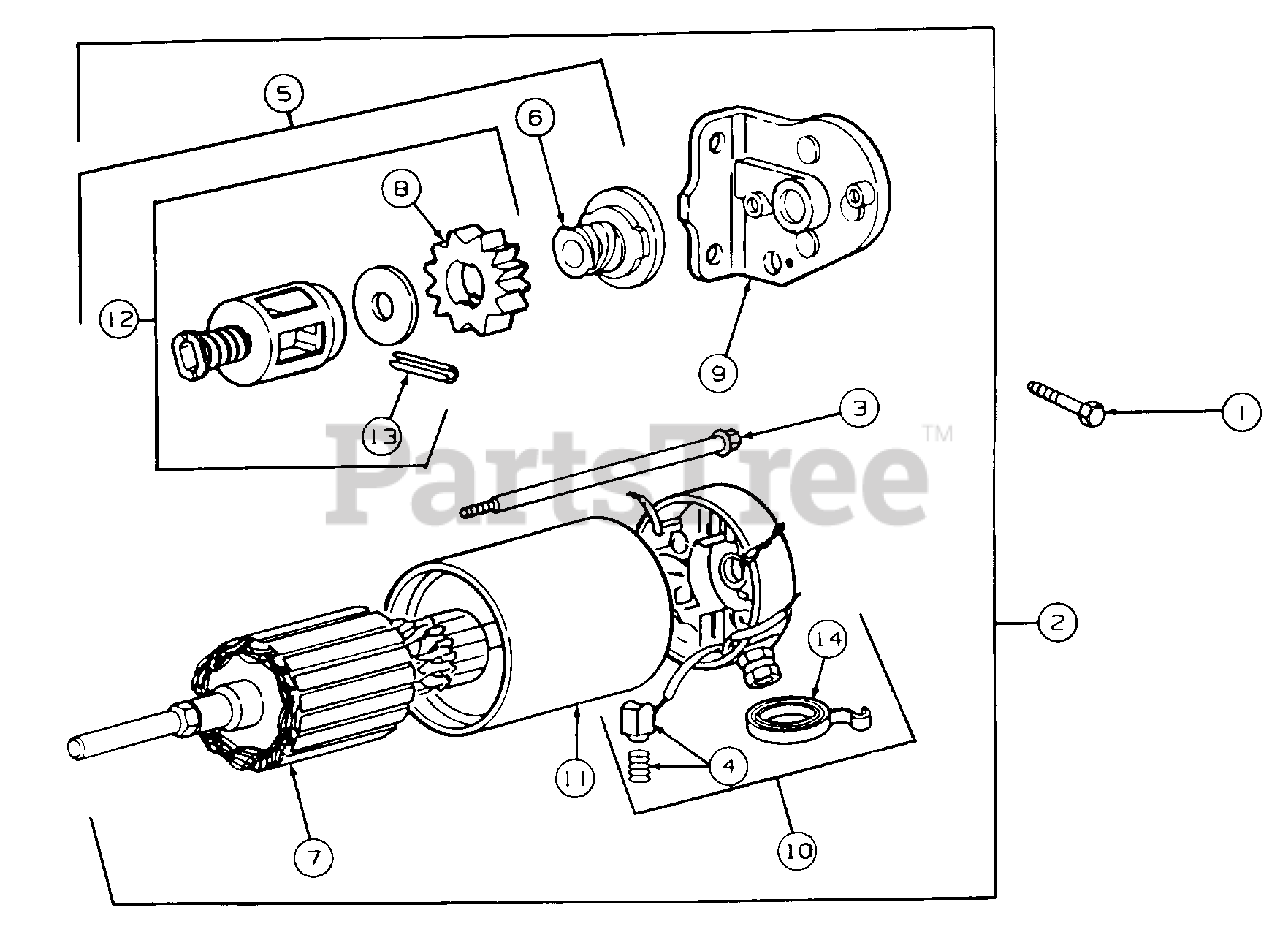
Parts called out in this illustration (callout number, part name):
1	Screw, Mounting
2	Motor, Starting
4	Brush Assy
5	Kit, Bendix Drive
6	Drive, Starter
7	Armature Assy
8	Gear
10	Cap Assy, Commutator End
11	Housing Assy
12	Kit, Spring
13	Pin, Roll
14	Spring, Brush
